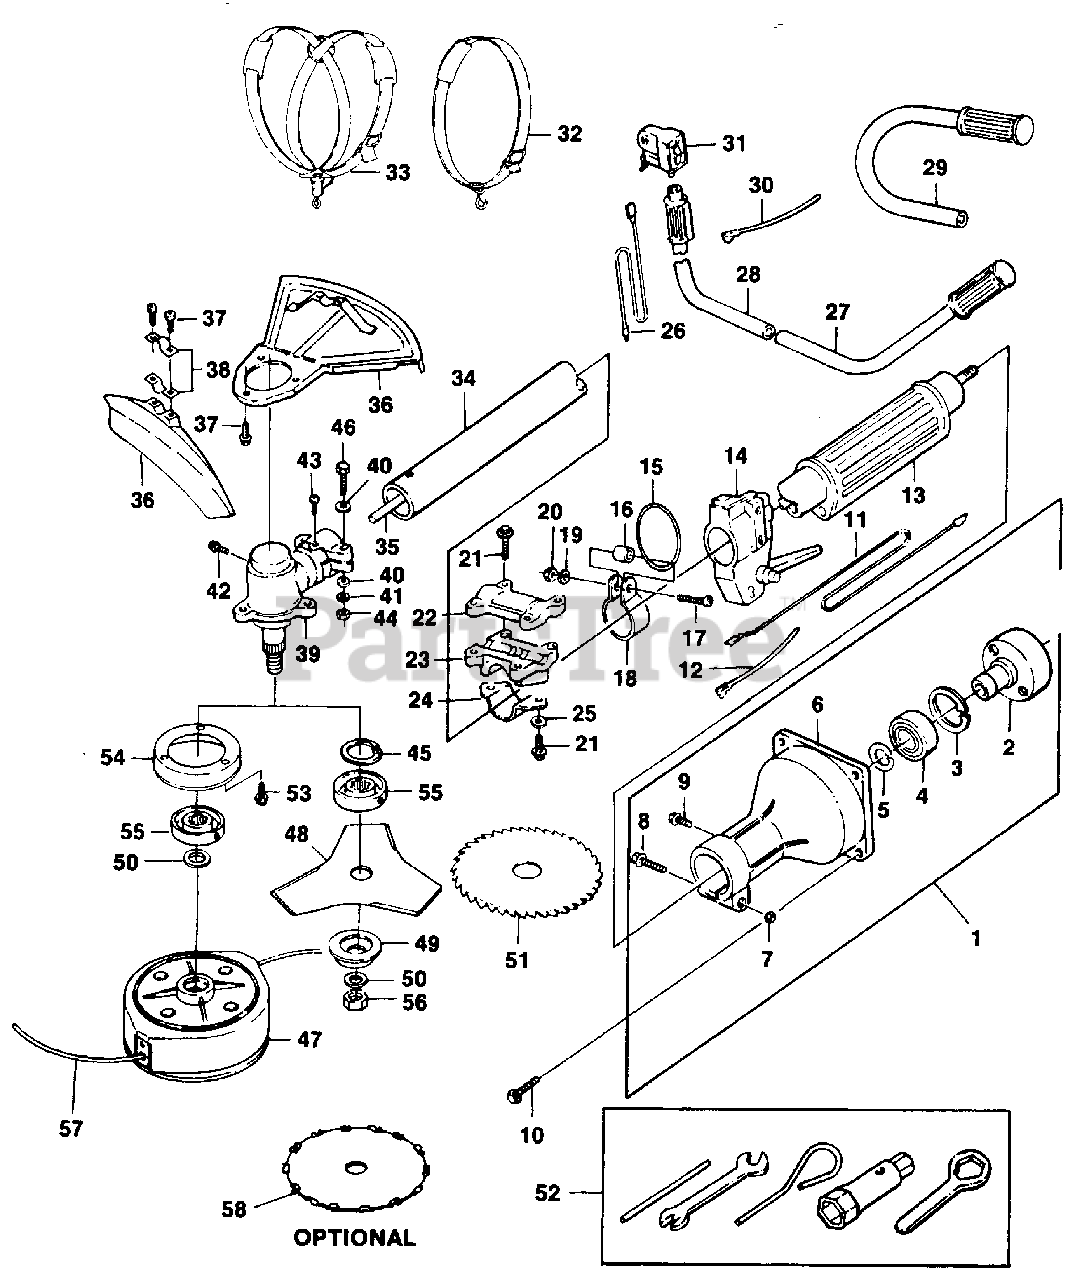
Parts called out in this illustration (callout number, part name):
1	CLUTCH CASE ASSY.
2	DRUM- Clutch
3	RING- Stop
4	BEARING- Ball
5	RING- Stop
6	CASE- Clutch
11	WIRE- Lead
12	Not Used On This Model
14	Not Used On This Model
15	RING- Hanger
19	WASHER- Spring
20	NUT
21	BOLT- w/Washer
22	BRACKET- Top
23	BRACKET- Upper
24	BRACKET- Lower
25	Not Used On This Model
26	Not Used On This Model
27	Not Used On This Model
28	Not Used On This Model
29	U-HANDLE
30	Not Used On This Model
31	Not Used On This Model
33	Not Used On This Model
34	PIPE ASSY
35	DRIVESHAFT
39	GEAR CASE ASSY.
40	WASHER- Flat
41	WASHER- Spring
44	NUT
45	RING- Stop
47	STRING HEAD ASSY.
48	TRI ARC BLADE
49	FLANGE- Lower
50	WASHER- Special
51	Not Used On This Model
55	FLANGE- Upper
56	BLADE- Nut
57	LINE- .105" Dia. (250 ft.)
58	MACHETE BLADE - (7")
